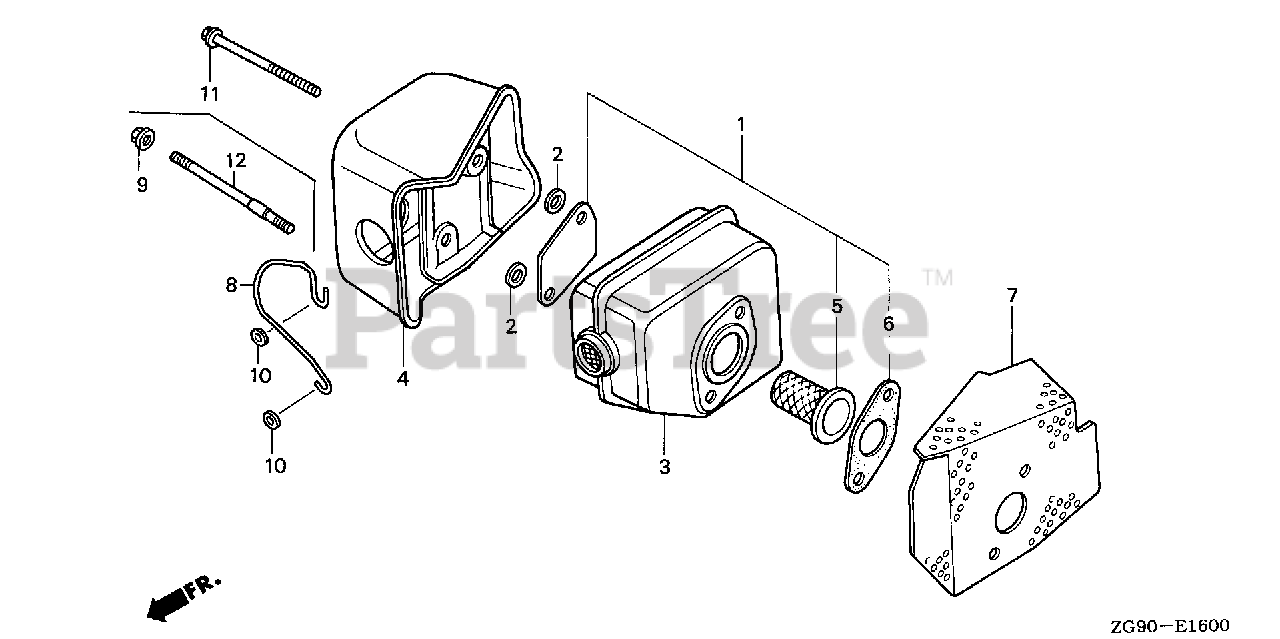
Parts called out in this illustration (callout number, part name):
1	ARRESTER KIT, SPARK
3	MUFFLER
4	PROTECTOR, MUFFLER
5	ARRESTER KIT, SPARK
6	GASKET, MUFFLER
7	GASKET, MUFFLER
